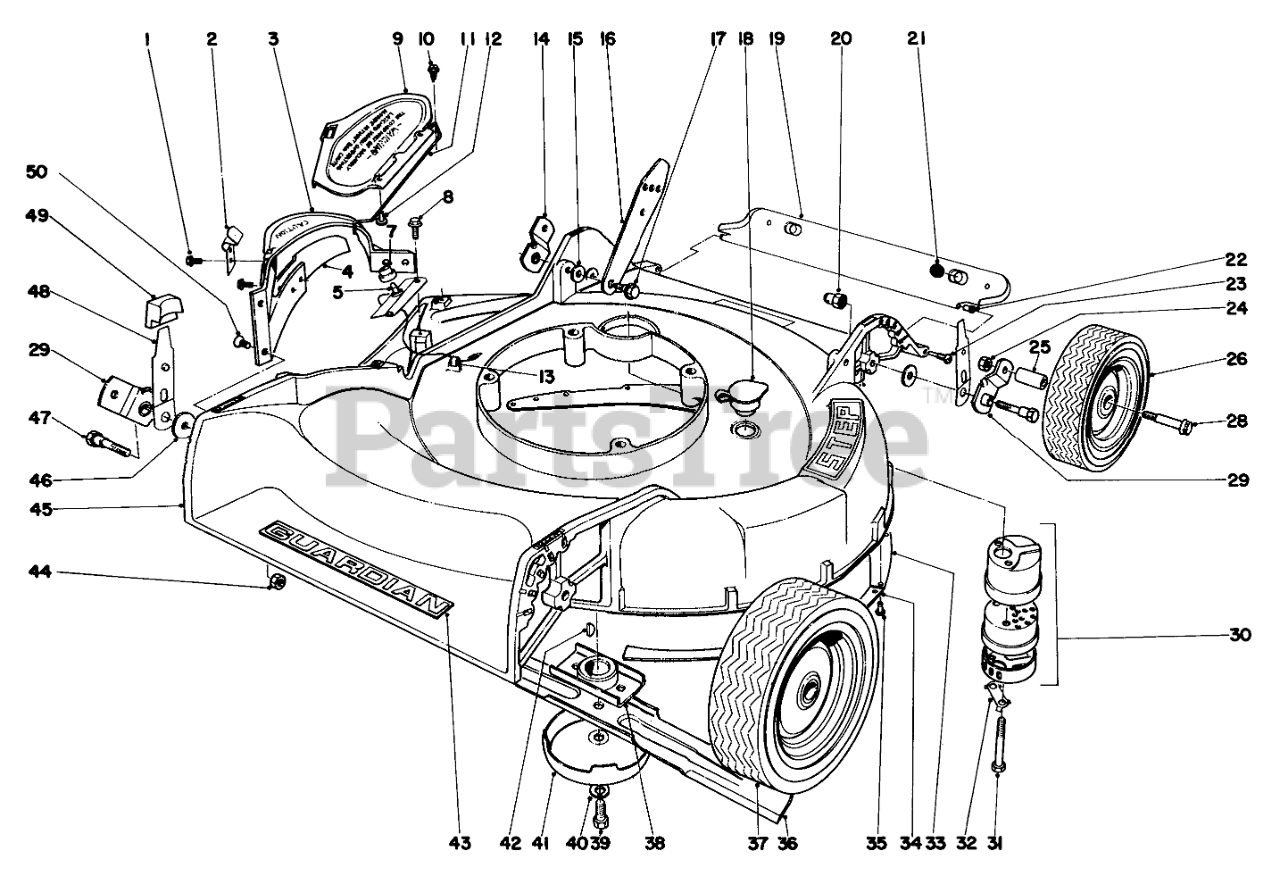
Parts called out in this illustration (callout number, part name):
2	Latch
3	Deflector (Incl. Ref. Nos. 1-4)
4	DefIector Bar
5	Deflector Switch & Wire (Incl. Ref. No. 7)
7	Boot Switch
9	Deflector Cover (Incl. Ref. Nos. 11 & 12)
10	SCREW
11	Hinge Pin
12	Rivet
14	Pivot Arm
15	SPACER
16	Handle Latch
17	SCREW-SHOULDER
18	WASHOUT PLUG
19	Rear Safety Shield (Incl. Ref. Nos. 21 & 22)
20	HANDLE PIVOT NUT
21	SKID BUTTON
22	SAFTEY SHIELD BUSHING
23	SAFTEY SHIELD SCREW
24	Nut
25	Bushing
26	Wheel Assembly
29	Pivot Arm
30	Muffler (Incl. Ref. Nos. 31 & 32)
31	SCREW-HH
32	CLIP - LOCKING
33	Main Skirt
34	Secondary Skirt
36	Blade
37	Wheel Assembly
38	BLADE RETAINER WA
39	SPECIAL SCREW
40	WASHER-LOCK
41	AntiScalp Cup
42	KEY-WOODRUFF
43	Emblem
44	Nut
45	Housing (Incl. Ref. Nos. 33, 34, 35)
46	WASHER-PIVOT
47	5/16-18 PIVOT SCREW
48	Spring Arm
49	Knob
50	Screw
